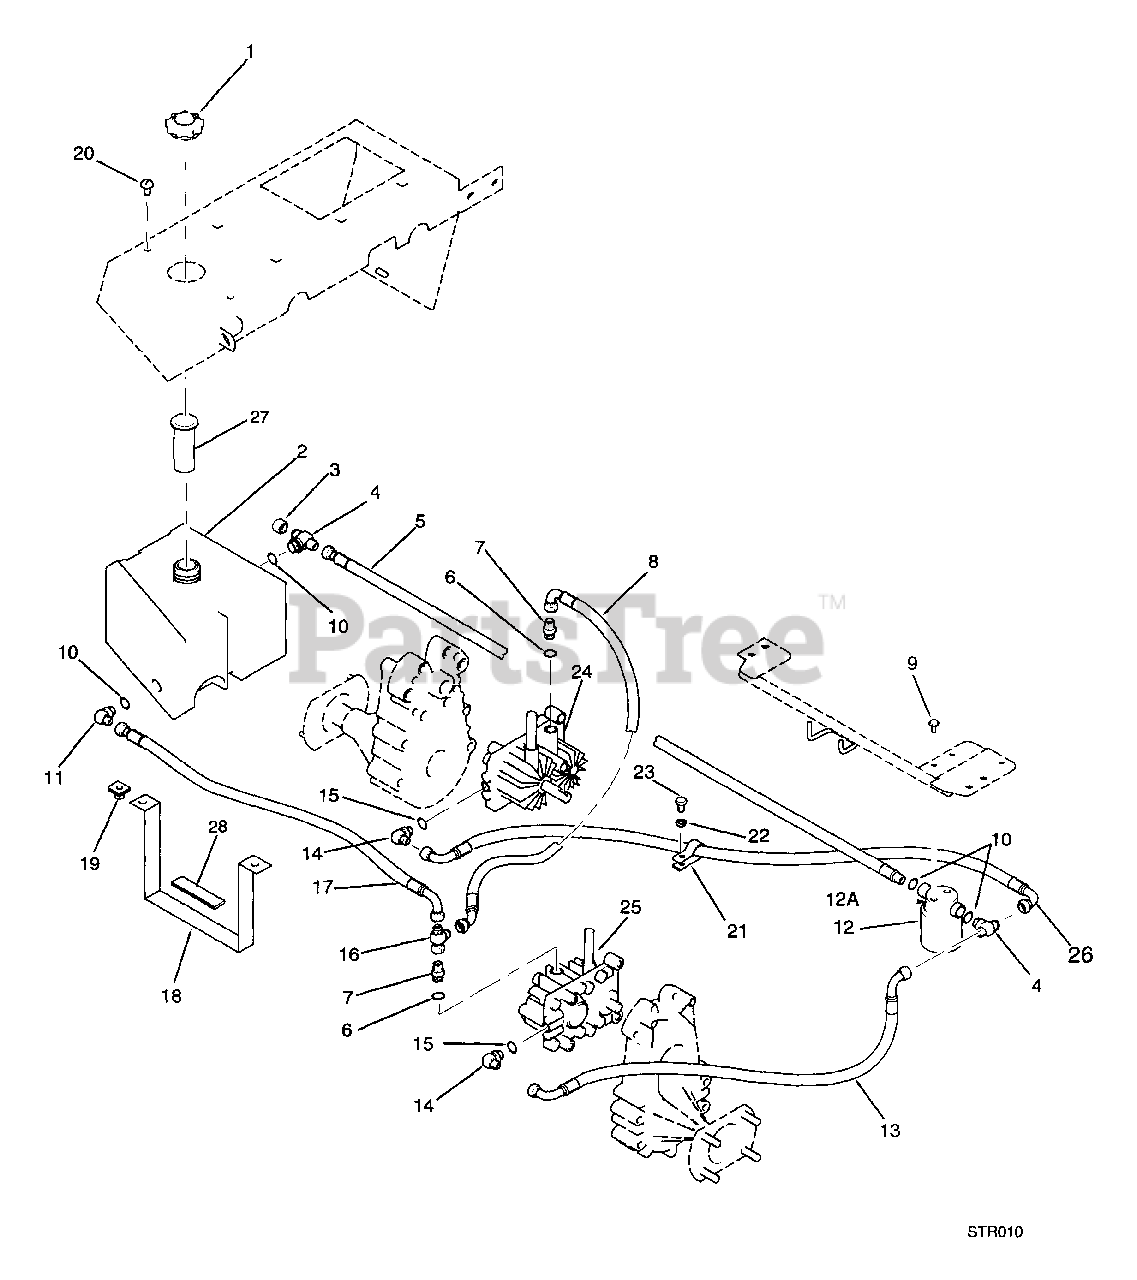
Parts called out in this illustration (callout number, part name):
1	Cap, Hydraulic Reservoir Fill
2	Tank, Hydraulic Oil
3	Cap, 3-4-16 JIC
4	Tee, 3/4-16 JIC x O-Ring
5	Hose Assembly, Filter inlet
6	O-Ring, 3/32 x 3/4 ID
7	Union, Tube
8	Hose Assembly, Case Drain
9	Serr. Fl. Hex Head CPSCRW, 1/4-30 x 1/2"
10	O-Ring, 3/32 x 5/8 ID
11	Elbow, 90ø JIC to O-Ring
12	Element, Filter
12A	Head, Filter
13	Hose Assembly, L.H. Charge Pump
14	Elbow, 90ø 9/16-18 JIC to 7/16-20 O-Ring
15	O-Ring, 1/16 x 3/8 ID
16	Tee, 3/4-16 Swivel
17	Hose Assembly, Case Drain Return
18	Strap, Hydraulic Tank
20	Machine Screw, Round Head, 1/4-20 x 2.00"
21	Clamp, Cable
22	Lockwasher, 3/8"
23	Bolt, Hex Head, 3/8-16 x 3/4"
24	Pump, R.H.
25	Pump, L.H.
26	Hose Assembly, RH Charge Pump
27	Insert, Filler Neck
28	Rubber Pad
